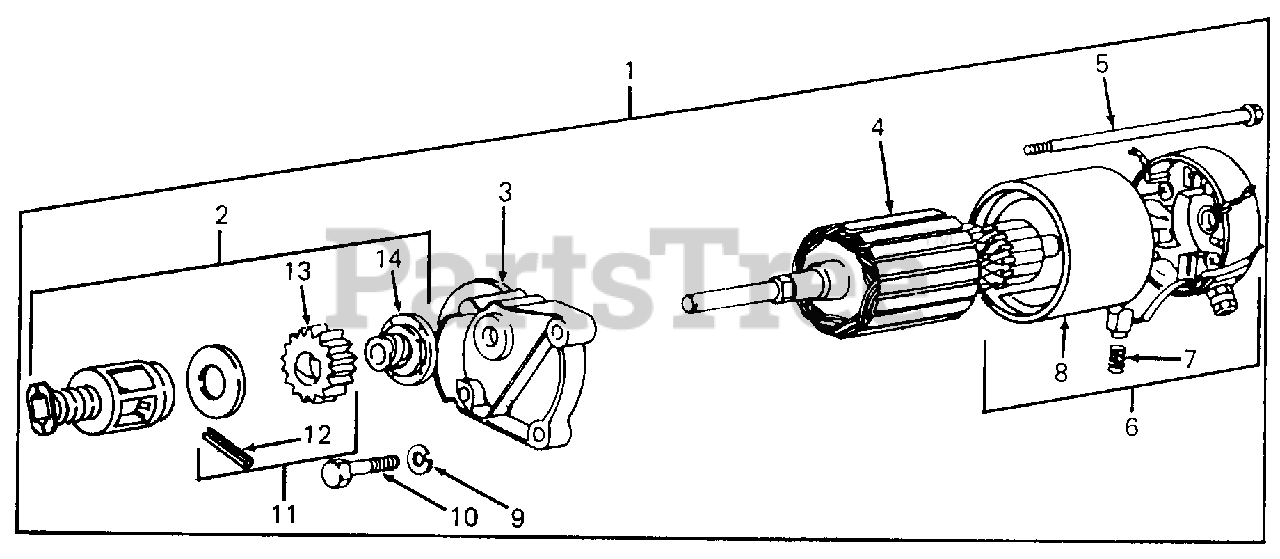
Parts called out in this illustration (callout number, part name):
1	Motor and Drive Assembly
2	Starter Drive Group
3	End Cap Assy, Drive
4	Armature Assy
5	Thru Bolt
6	End Cap Assy, Commutator
7	Brush Assy
8	Housing Assy
9	Lockwasher
10	Screw, Hex Hd 5/16-18 X 1-1/2
11	Pinion Spring Kit
12	Pin, Roll
13	Gear
14	Clutch Assy
